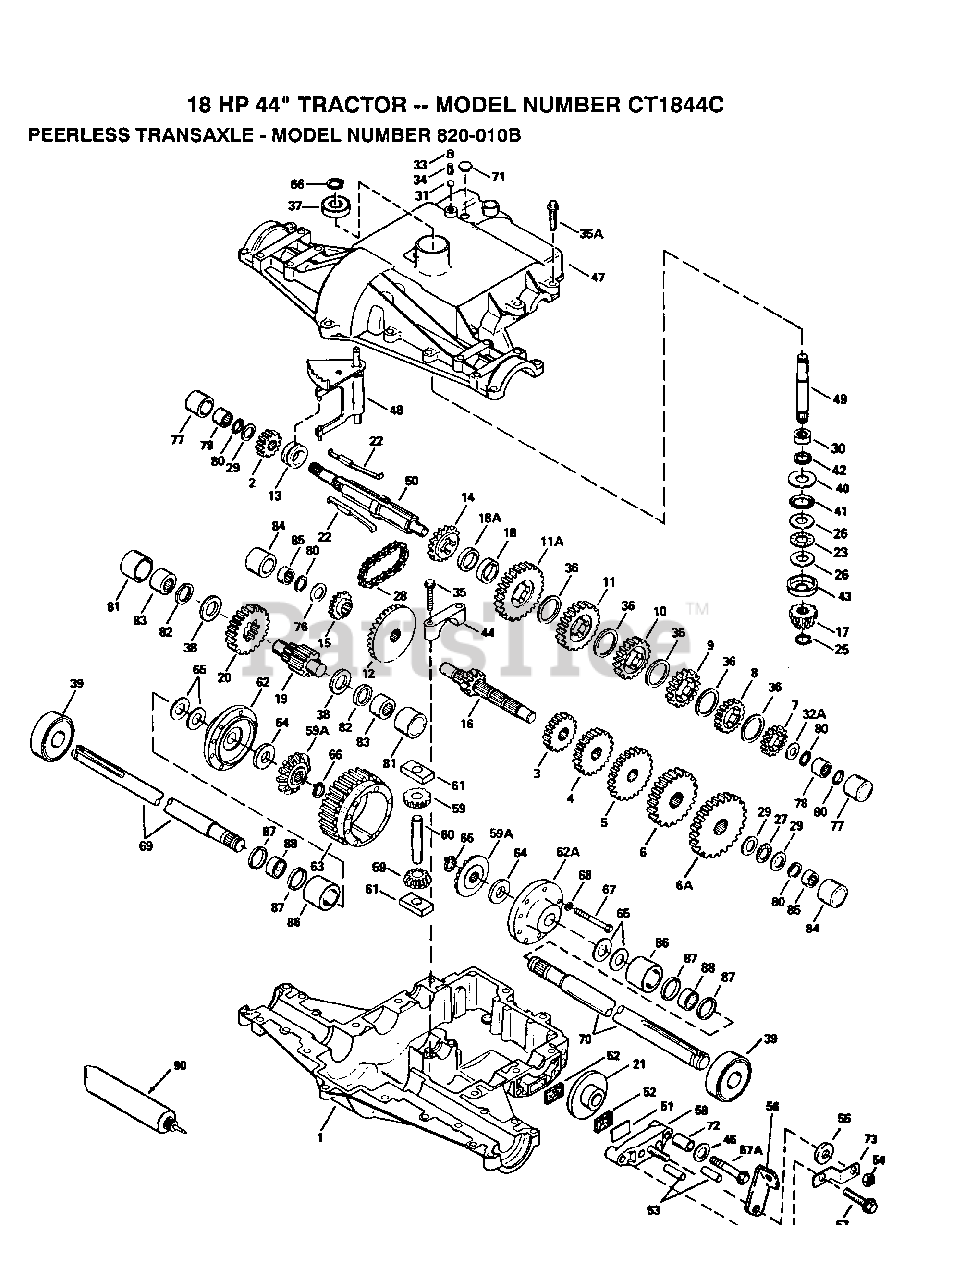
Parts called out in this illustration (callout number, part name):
1	CASE TRANSAXLE
2	GEAR, SPUR, 15T
3	GEAR, SPUR, 12 TEETH
4	GEAR, SPUR, 15T
5	GEAR, SPUR, 20T
6	GEAR, SPUR, 28T
6A	GEAR, SPUR, 31T
7	GEAR, SPUR, 19 TEETH
8	GEAR, SPUR, 22T
9	GEAR, SPUR, 30T
10	GEAR, SPUR, 35T
11	GEAR, SPUR, 37 TEETH
11A	GEAR, SPUR, 41T
12	GEAR BEVEL, 33T
13	COLLAR SHIFT
14	SPROCKET 18T (REV)
15	SPROCKET 9T
16	SHAFT COUNTER
17	BEVEL PINION, 13T
18	SPACER, .350/.340 THICK
18A	SPACER, .276/.268 THICK
19	SHAFT, OUTPUT, 9T
20	GEAR, OUTPUT, 35T
23	BEARING THRUST
25	RETAINING RING
26	WASHER THRUST
27	THRUST BEARING
28	CHAIN, ROLLER
29	WASHER THRUST
30	BEARING NEEDLE
31	BALL STEEL, 5/16" DIA.
32	WASHER THRUST
33	SCREW, 3/8-16 X 3/8"
35	SCREW, 1/4-20 X 1-1/4
35A	SCREW HEX HD 5/16-18 X 1-1/4
36	WASHER THRUST
37	BEARING BALL
38	WASHER THRUST
39	BEARING BALL
42	OIL SEAL 3/4
43	WASHER CUPPED
44	BEARING CAP
45	WASHER FLAT
47	COVER TRANSAXLE
48	ROD AND FORK ASSY SHIFT
49	SHAFT INPUT
50	SHAFT BRAKE
51	PLATE BRAKE PAD
54	LOCKNUT 5/16-24
55	WASHER, FLAT
56	LEVER BRAKE
57	SCREW, 1/4-20 X 1-1/4
57A	SCREW FLNG HEX 1/4-20 X 2-1/4
58	HOLDER BRAKE PAD
59	PINION, 10T
61	BLOCK DRIVE
62	CARRIER DIFF THREADED HOLES
63	GEAR, RING, 31T
65	WASHER THRUST
67	SCREW, 1/4-20 X 2-1/4
68	WASHER LOCK 1/4
69	AXLE, 12-5/16" LONG
70	AXLE, 16-3/16" LONG
71	PLUG, THRDED, 9/16-18
73	BRKT BRAKE LEVER
78	BEARING NEEDLE
79	BEARING NEEDLE
81	SLEEVE STEPPED
82	RING SQ CUT
83	BEARING NEEDLE CAPPED
84	SLEEVE STEPPED
85	BEARING NEEDLE CAPPED
86	SLEEVE STEPPED
87	RING SQ CUT
88	BEARING NEEDLE
90	GREASE BENTONITE, 32 OZ.
